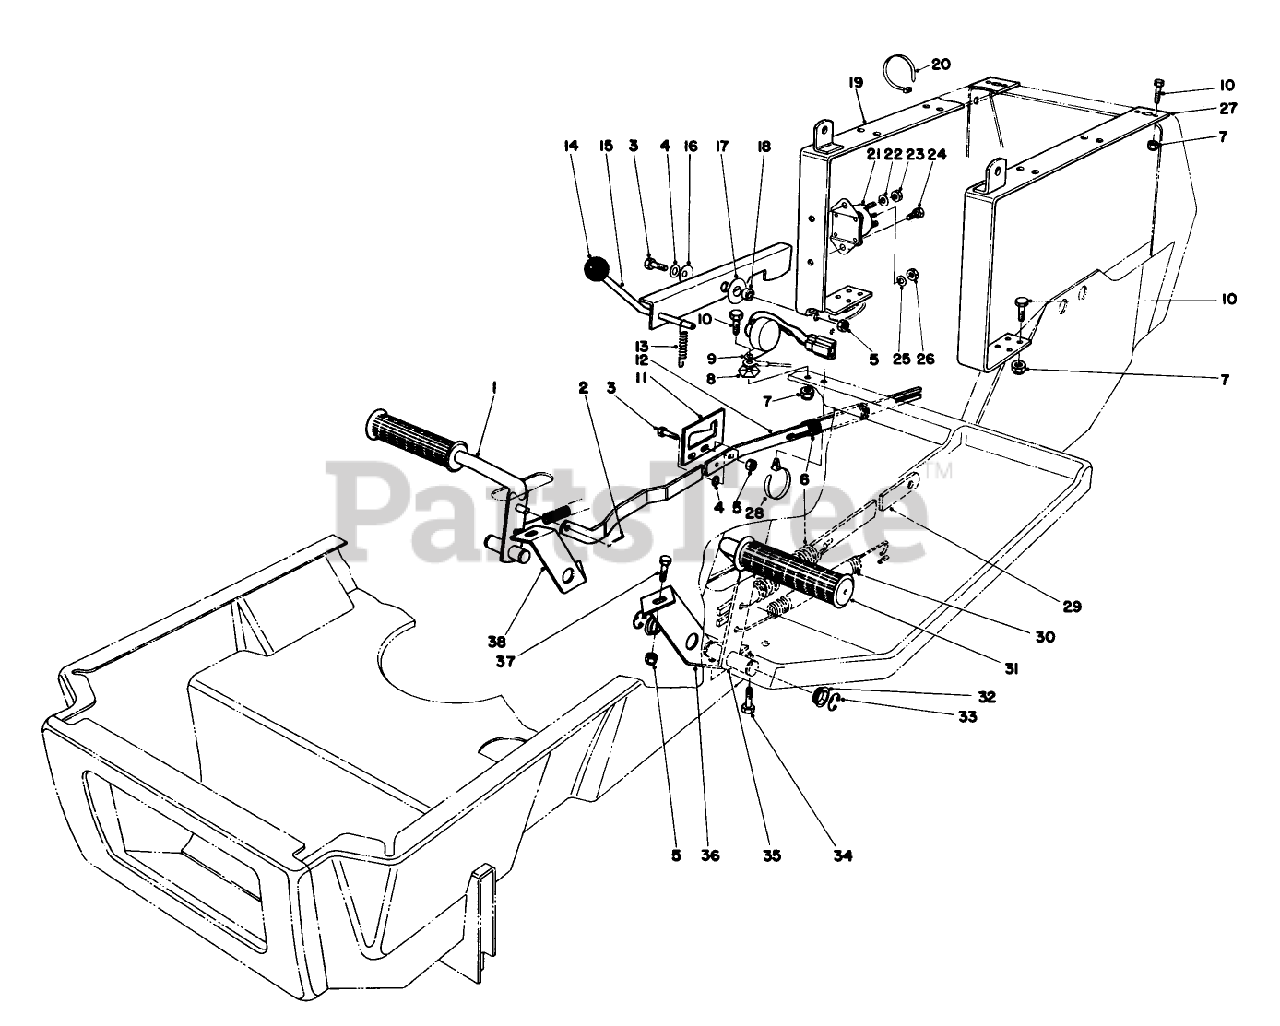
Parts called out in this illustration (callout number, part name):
2	PIN-COTTER
3	Screw
4	WASHER-PLAIN
5	NUT-LOCK, NI
10	Bolt
14	Knob
16	Belleville Washer
17	WASHER-PLASTIC
20	TIE-CABLE
21	Solenoid
22	Lockwasher
23	NUT-JAM, BRASS
24	SCREW-HWH
25	NUT-HEX
26	WASHER-LOCK
28	TIE-MOUNT, PUSH
30	SPRING-EXTENSION
33	E-RING
34	SCREW-TAPTITE
35	CLUTCH PEDAL WA *BO
37	SCREW-HH
